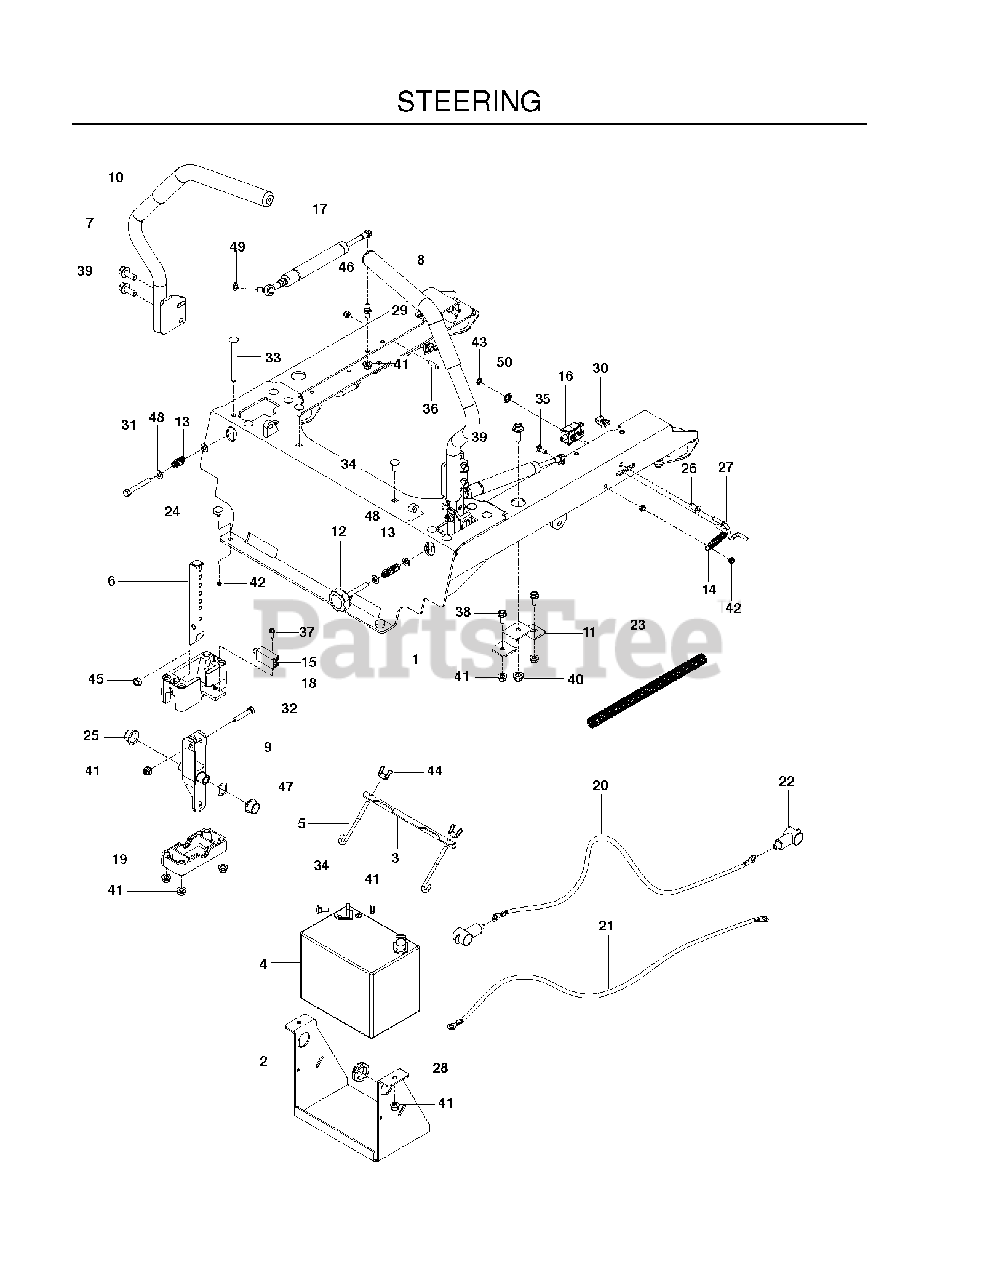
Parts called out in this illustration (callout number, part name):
1	FRAME, SEAT MOUNT, ORG
2	BRACKET, BATTERY, BLK
3	BRACKET, BATTERY MOUNT
4	BATTERY, 12 V 330 AMP
6	LEVER, MOTION
7	LEVER, W/GRIP, RT
8	LEVER, W/GRIP, LT
9	LEVER, CONTROL
10	GRIP - DRIVE LEVER 12"
11	MOUNT, MID-SECTION, BLK
14	SPRING, EXTENSION
15	SWITCH, INTERLOCK
16	SWITCH, BRAKE 3P
17	ASSEMBLY, DAMPENER
18	BLOCK, UPPER
19	BLOCK, LOWER
20	CABLE, POSITIVE, 55"
21	CABLE, NEG, 55"
23	LOOM, SPLIT, CONVOLUTED
24	BUMPER, 1/4-20 STUD, 1/4
25	BEARING, FLANGE
26	BUSHING, 1/4 FLANGE
27	LINK, SWITCH
28	RUBBER GROMMET
29	STUD.BALL.10MM
30	U-CLIP 5/16-18 NUT RETAINER
31	HCS 5/16-18 X 2 1/2 TPBLT
32	HCS 5/16C X 1 3/4
33	RHSNB 5/16-18 X 3-3/4 GR 5 ZD
34	BOLT 5/16C X 3/4" CARRIAGE
35	RHSNB 1/4C X 3/4
36	SCR #10-24 X .75 SKT HD BLK
37	SCREW #10 X 1/2 SELF TAPPING
38	HHFS 5/16-18 X 3/4
39	HHFS 3/8-16 X 1 GRD 5 ZD
40	NUT 3/8-16 HEX FLG NYLOC ZD
41	5/16-18 NYLOC FLANGE NUT
42	JAM NUT 1/4C (2 2 PW01)
44	WING NUT 1/4
45	NUT 5/16C HEX
46	NUT 10-24 NYLOC
47	WASHER, .825 X 1.087, WAVE
48	FLAT WASHER 5/16 SAE
49	WASHER 5/16 LOCK
50	NUT 3/8 PALNUT RTNG BLK PHOS
